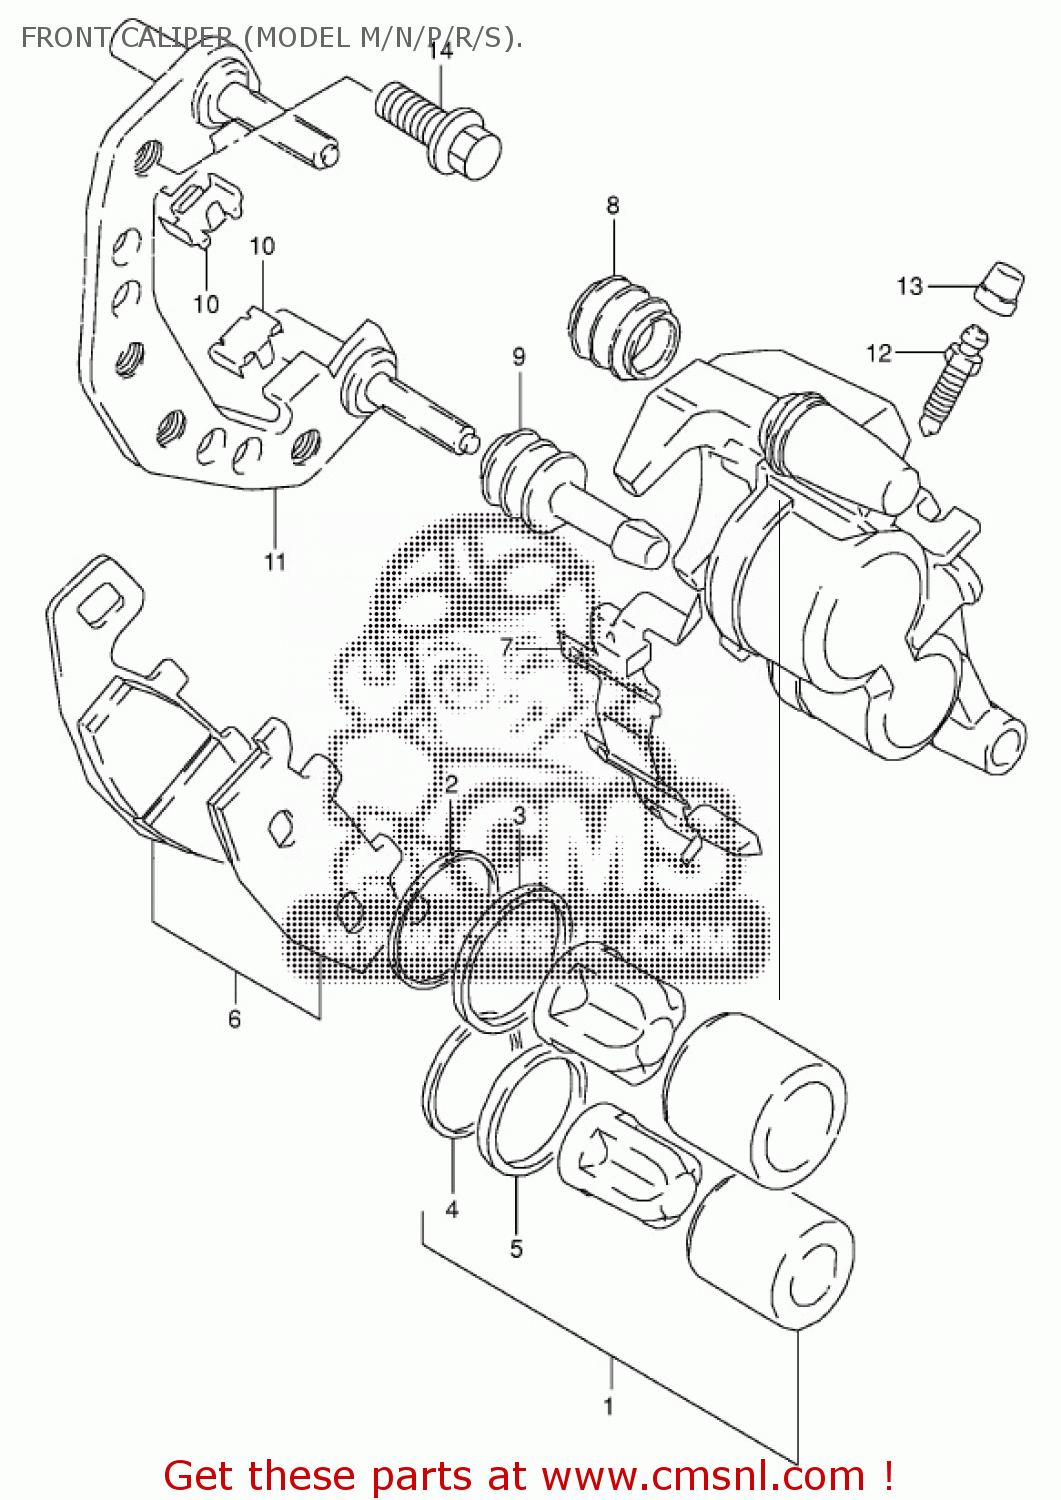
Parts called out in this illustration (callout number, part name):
1	PISTON SET
2	SEAL,PISTON
3	SEAL,WIPER
4	SEAL,PISTON
5	SEAL,WIPER
6	PAD SET (NAS)
7	SPRING,PAD
8	BOOT,AXLE
9	INSULATOR,AXLE
10	GUIDE,PAD
11	CARRIER,CALIPER
12	BLEEDER
13	CAP,BLEEDER PLUG
14	BOLT
